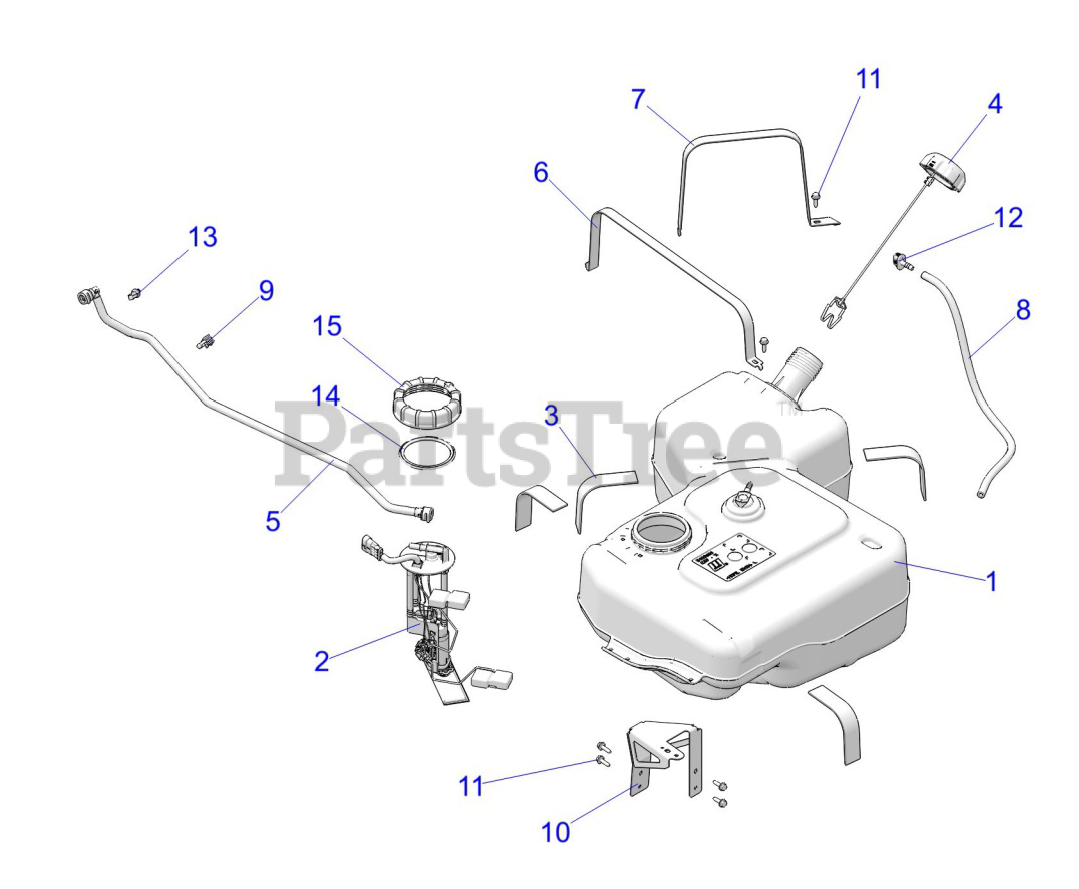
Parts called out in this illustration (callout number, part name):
1	ASM-FUEL TANK
2	ASM-FUEL PUMP
3	PAD, BATTERY
4	CAP-GAS TANK,TETHER
5	ASM-FUEL LINE
6	BRKT-TANK,STRAP,INSIDE,GALV
7	BRKT-TANK,STRAP,OUTSIDE,GALV
8	FUEL LINE-54 CENTIMETRS
9	CLIP-EDGE,SIDE W/STRAP
10	BRKT-FUEL TANK,SUPPORT,BLK
11	SCR-TXTH-M6X1.0X25 RIE
12	FITTING-VENT LINE
13	CLIP-ROUTING
15	NUT, JAM
